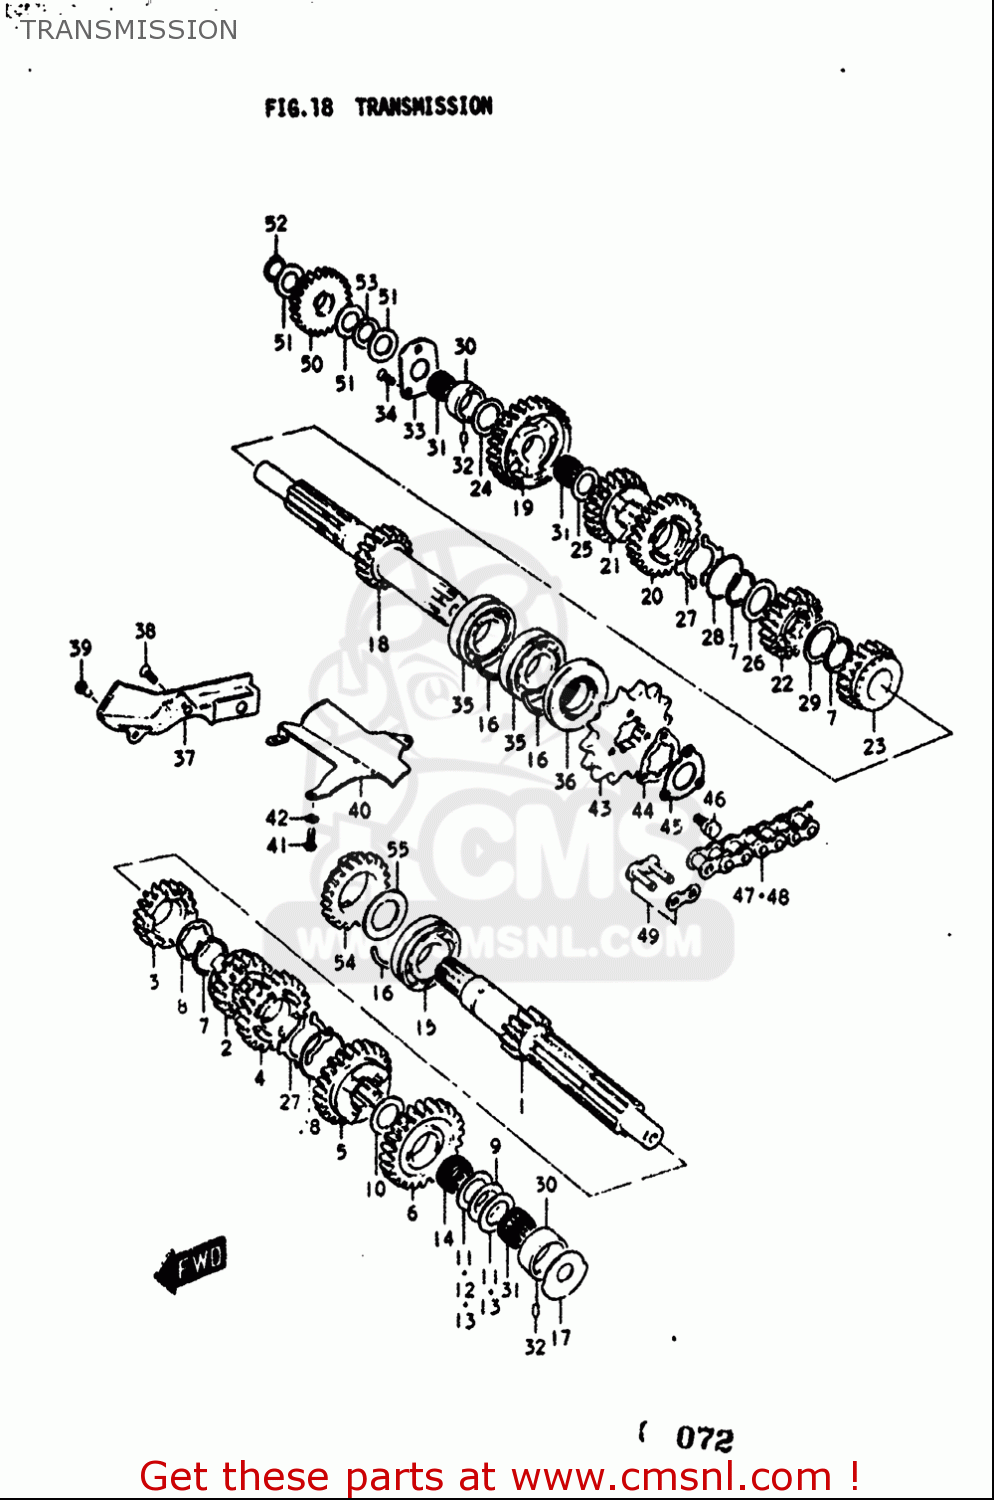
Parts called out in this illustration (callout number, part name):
7	RING,SNAP
8	WASHER
9	WASHER(17X29X1)
10	SHIM(17X30X1)
11	WASHER(21X30X1)
12	WASHER
13	WASHER
14	BEARING(17X21X9.8)
16	C RING
25	SHIM(17X30X1)
26	WASHER
28	CIRCLIP
29	WASHER
30	BUSHING
31	BEARING(17X21X12.8)
32	PIN
34	SCREW
35	BEARING
36	SEAL,OIL(25X52X7)
38	SCREW
39	SCREW
41	SCREW
42	WASHER,LOCK
43	SPROCKET,ENGINE
44	PLATE,ENGINE SPROCKET
45	WASHER
46	BOLT
51	SHIM(17X30X1)
52	CIRCLIP
53	WASHER
55	WASHER(25X41X3)
